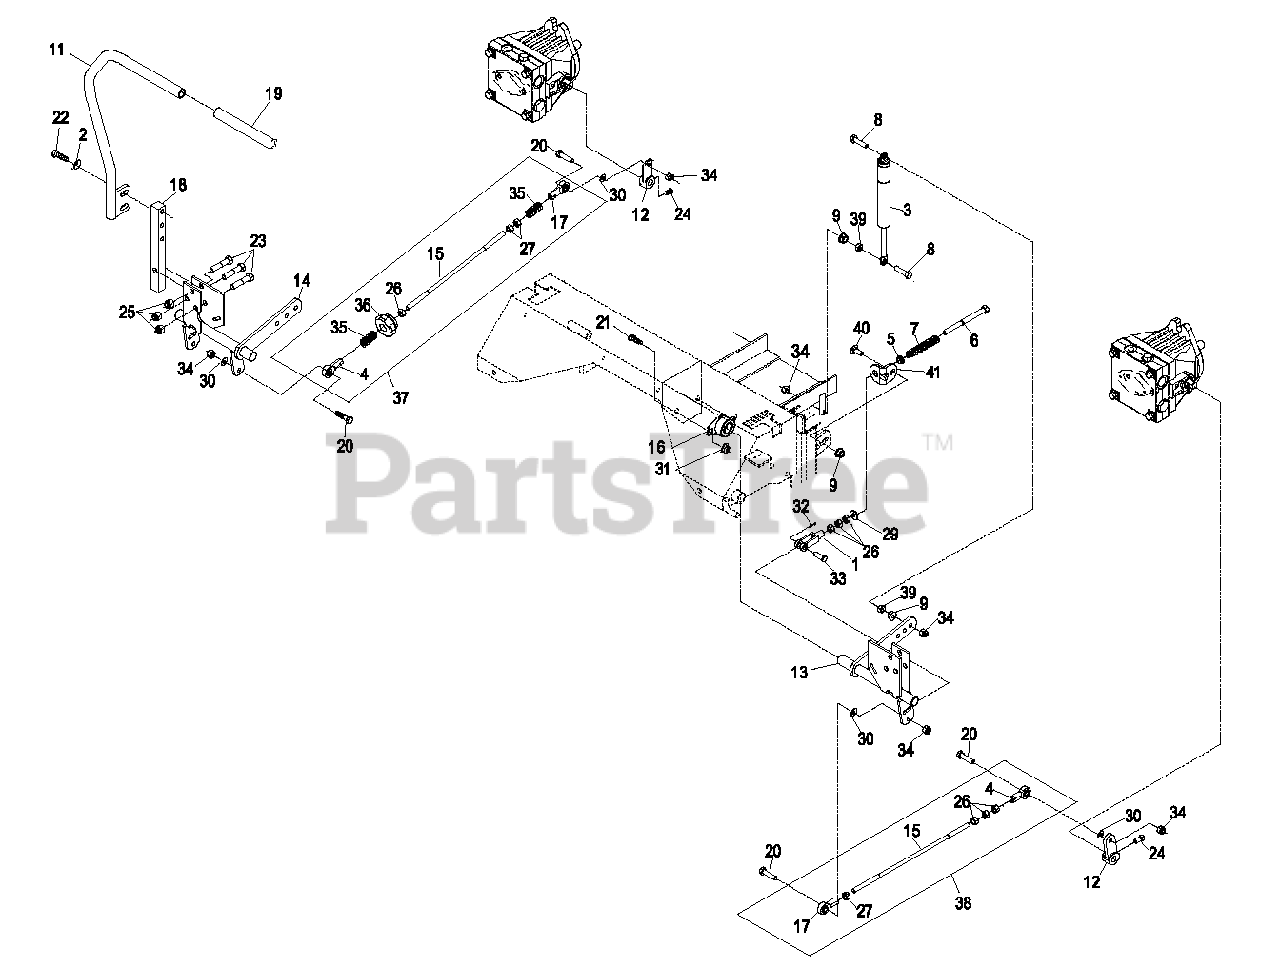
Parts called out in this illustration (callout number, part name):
1	YOKE-ADJUSTABLE
2	WASHER-BELLEVILLE
3	DAMPER-CONTROL, MOTION
4	BALLJOINT-RH
5	BUSHING-NYLON, FLANGED
6	BOLT-RETURN, NEUTRAL
7	SPRING-RETURN, NEUTRAL
8	SCREW-HH
11	ASM.RH LEVER/GRIP
12	ARM-CONTROL, PUMP
13	CONTROL-MOTION, LH
15	LINK-ROD, TRACKING
16	BEARING-FLANGE, SIDE
17	BALLJOINT-LH
18	ARM-SHAFT, CONTROL
19	GRIP,CONTROL LEVER
20	SCREW-HH
21	SCREW-HH
22	SCREW-HH
23	SCREW-HH
24	SCREW-SET
25	NUT-LOCK, NI
26	NUT-HEX
28	NUT-JAM
29	WASHER-FLAT
30	WASHER-FLAT
31	NUT-HHF, WHIZ
32	PIN-COTTER
33	PIN-CLEVIS
34	NUT-LOCK, NI
35	SPRING-COMPRESSION
36	KNOB-TRACKING
37	TRACKING ROD ASM
38	Asm, Tracking Rod
39	NUT-HEX
40	SCREW-CARR
41	TAB-ADJUSTMENT
